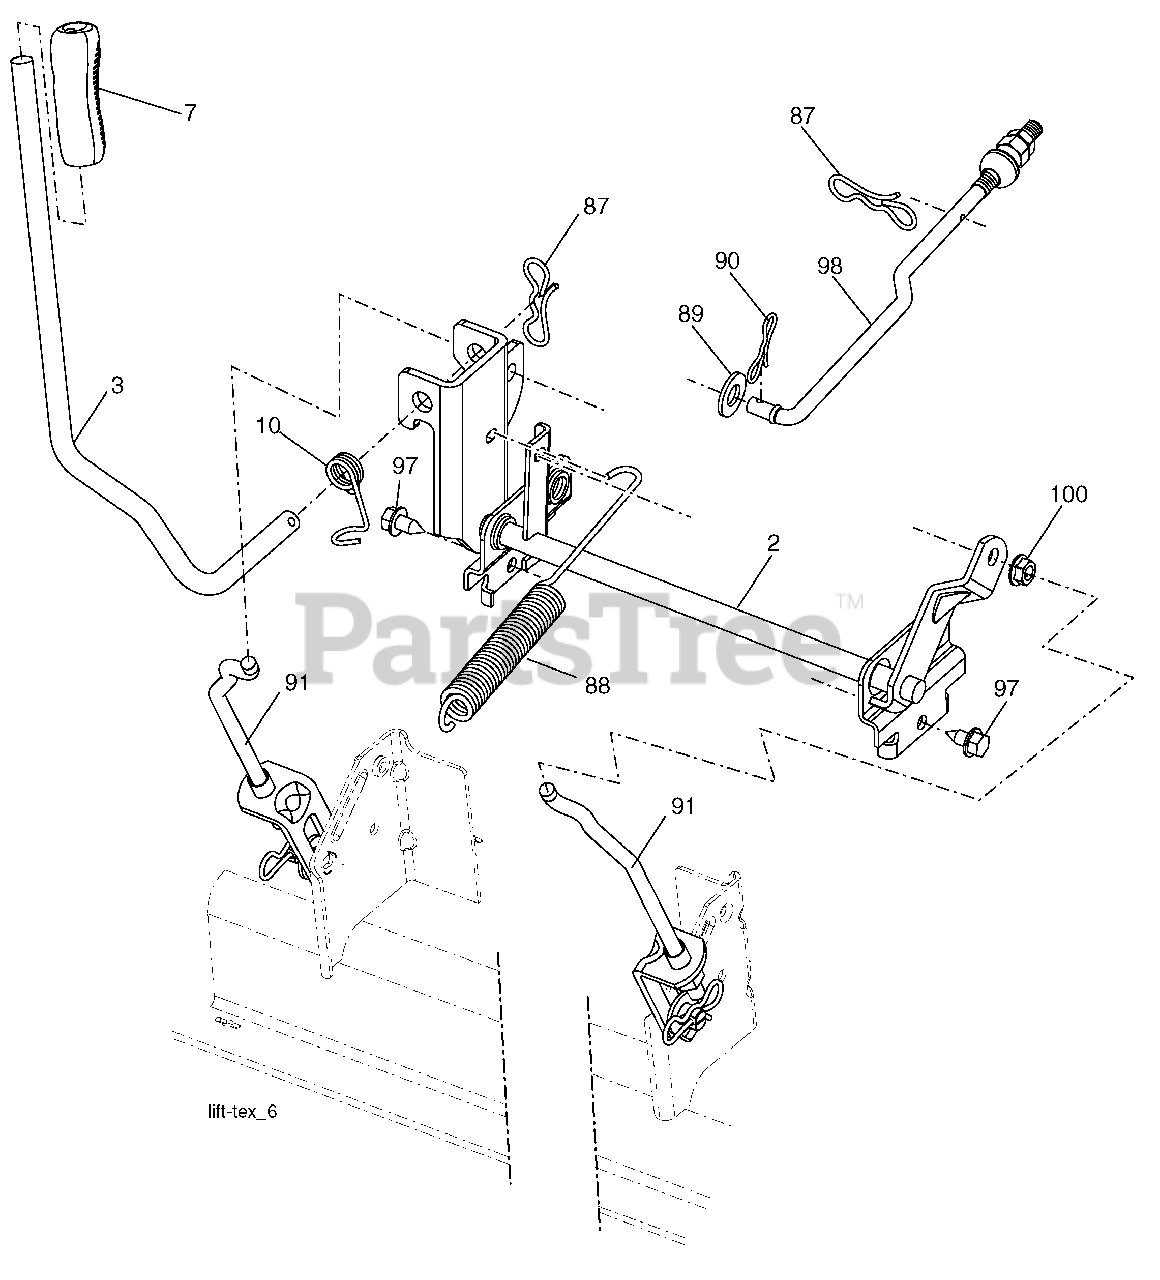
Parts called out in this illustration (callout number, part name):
2	Shaft Asm., Lift
3	Lever Asm., Lift RH
7	Grip, Lever
10	Spring Torsion
87	Pin Cotter 7/16 Bow Tie Lock
88	Spring Lift Assist
89	Washer Clear Zinc
90	Pin Cotter 5/16 Bow Tie Lock
91	Link Lift Susp Mower Rear
97	Screw 3/8-16 x .75 Smgml Tap/R.Z
98	Link Lift Susp. Front Mower
100	Nut Centerlock 3/8 -16 unc
